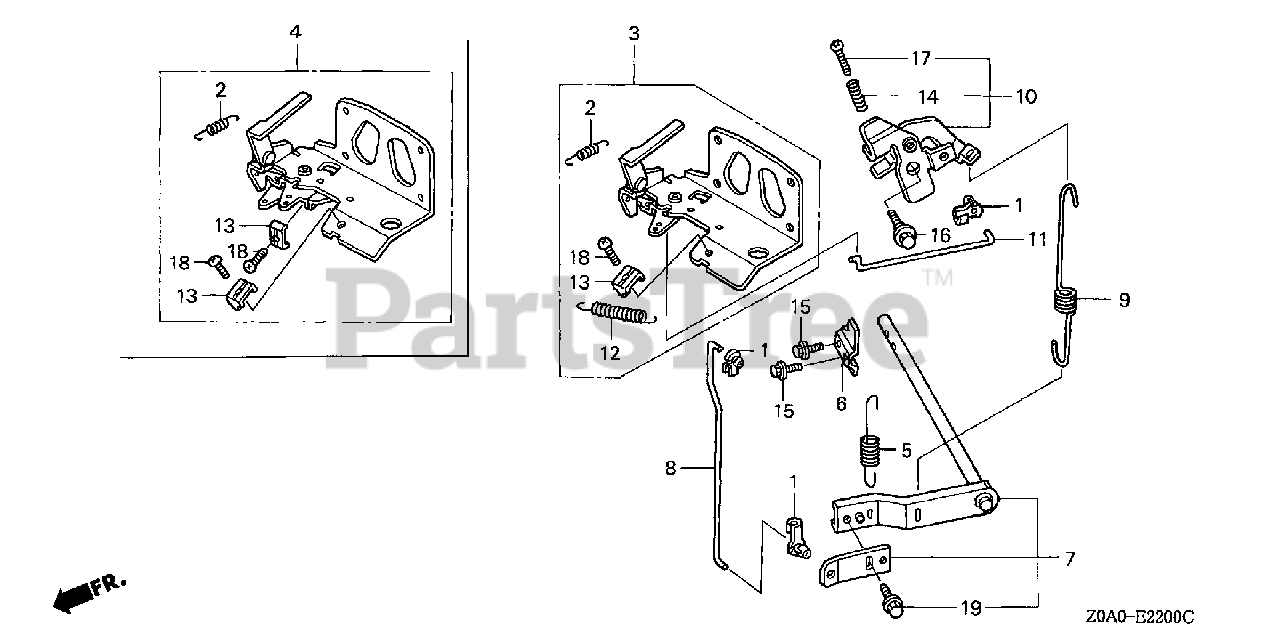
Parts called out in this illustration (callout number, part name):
1	ROD, JOINT
2	SPRING, CHOKE RETURN
4	CONTROL ASSY. (2-LEVER)
5	SPRING, STARTER
6	FORK, GOVERNOR
7	ARM, GOVERNOR
8	ROD, GOVERNOR
9	SPRING, GOVERNOR
10	LINK, GOVERNOR
11	ROD, GOVERNOR LINK
13	HOLDER, CABLE
14	SPRING, CONTROL ADJUSTING
15	BOLT, FLANGE (5X10)
16	BOLT, FLANGE (6MM) (CT200)
17	SCREW, RECESSED (5X25)
18	SCREW, PAN (5X16)
19	BOLT, FLANGE (6X10)
